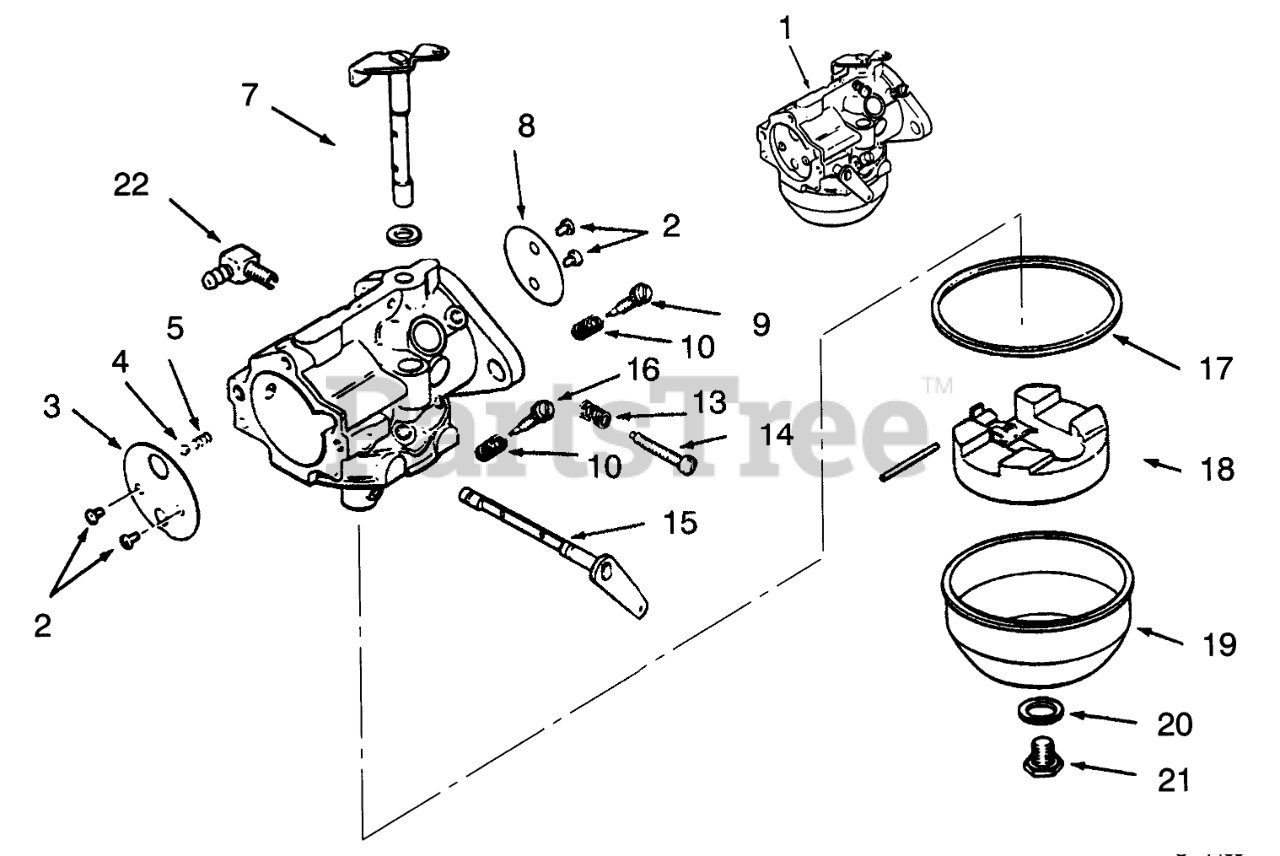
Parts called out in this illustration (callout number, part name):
1	Carburetor Assembly (Includes 5 thru 8)
2	Screw
3	Choke Plate
5	Spring
7	Shaft w/Lever & Seal
8	Plate-Throttle
9	Idle Fuel Adj. Needle
10	Spacer
13	Adj. Spring
14	Idle Speed Adj. Screw
15	Choke Shaft
16	Main-Needle
17	Gasket
18	Kit-Float (Incl. Pin)
19	Bowl-Fuel
20	Gasket
21	Screw
